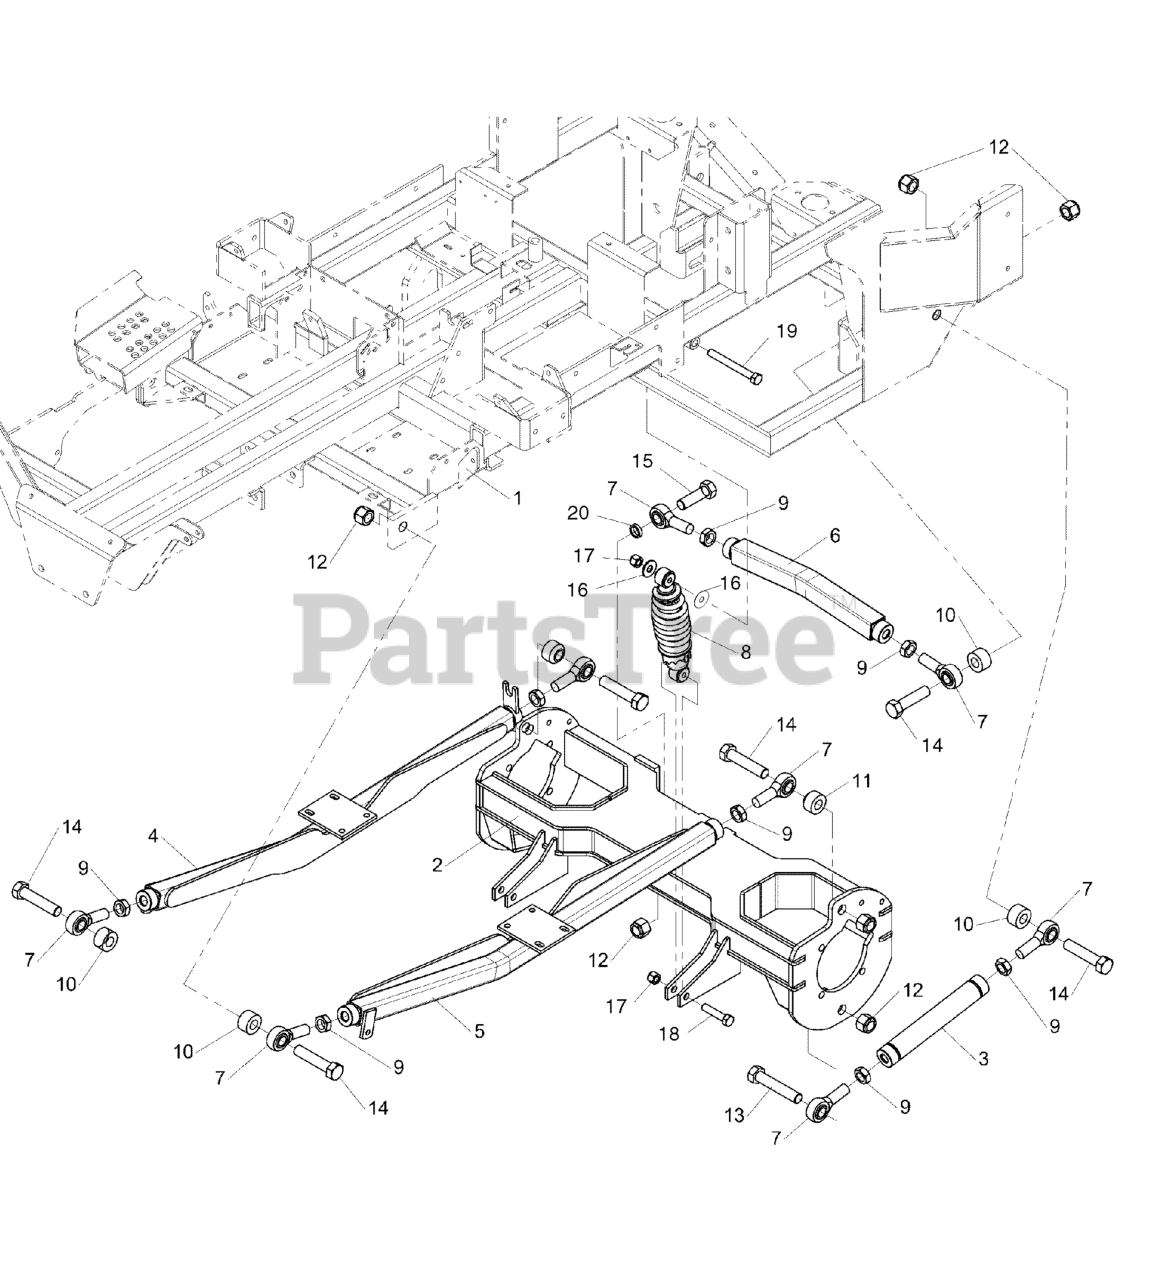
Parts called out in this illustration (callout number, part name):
1	MAIN FRAME
2	WELD, REAR END
3	WELD, REAR LINK
4	WELD, FRONT, LINK - RH
5	WELD, FRONT, LINK - LH
6	WELD, BAR, PANHARD
7	BALL JOINT, 3/4-16, MALE
8	SHOCK, REAR, IS4500
9	NUT, 3/4-16 HEX JAM
10	SPACER, .75 X 1.50 X .88
11	SPACER, .75 X 1.50 X 1.00
12	NUT, 3/4-16 HEX NYLON LOCK
13	BOLT, 3/4-16 X 4" YZ GD5
14	BOLT, 3/4-16 X 3-1/2" YZ GD5
15	BOLT, 3/4-16 X 2-1/2" YZ GD5
16	WASHER, 1/2" USS
17	NUT, 1/2-13 HEX NYLON LOCK
18	BOLT, 1/2-13 X 2-1/4" GD5 CZ
19	BOLT, 1/2-13 X 4-1/2" GD5
20	SPACER, .76 X 1.00 X .25
